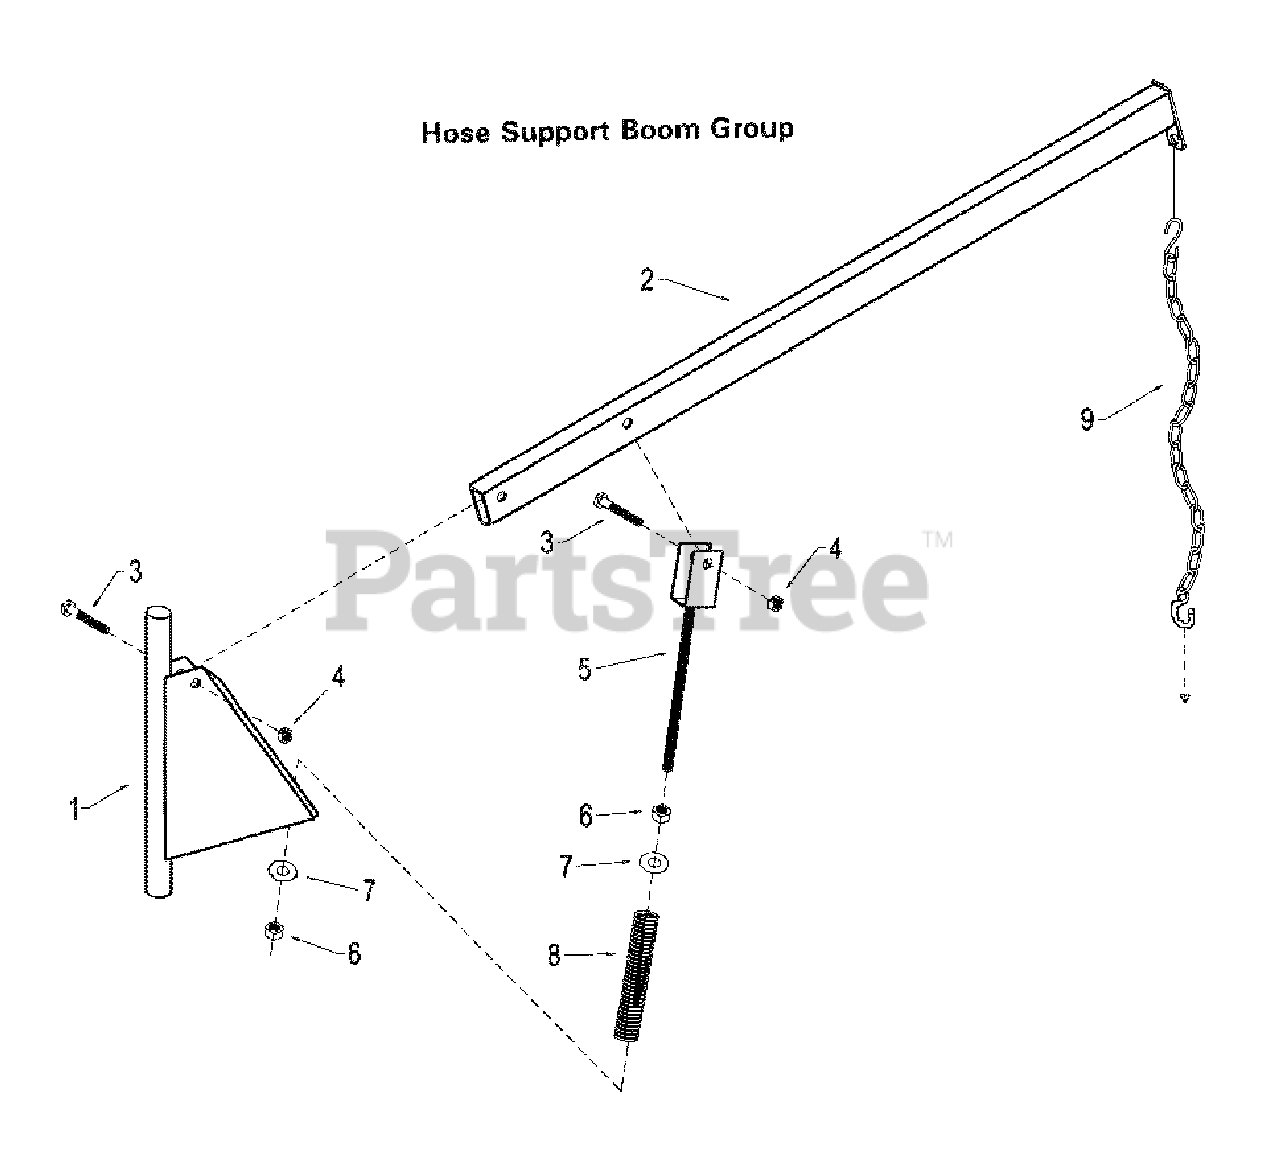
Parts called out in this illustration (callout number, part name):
1	Boom Vertical Member
2	Boom Horizontal Member
3	1/2-13 x 3" Hex Bolt
4	1/2-13 Lock Nut
5	Guide, Threaded Spring
6	3/4-10 Hex Nut
7	3/4 Flat Washer
8	Spring, Boom
9	Chain, Boom w/2 S-Hooks
